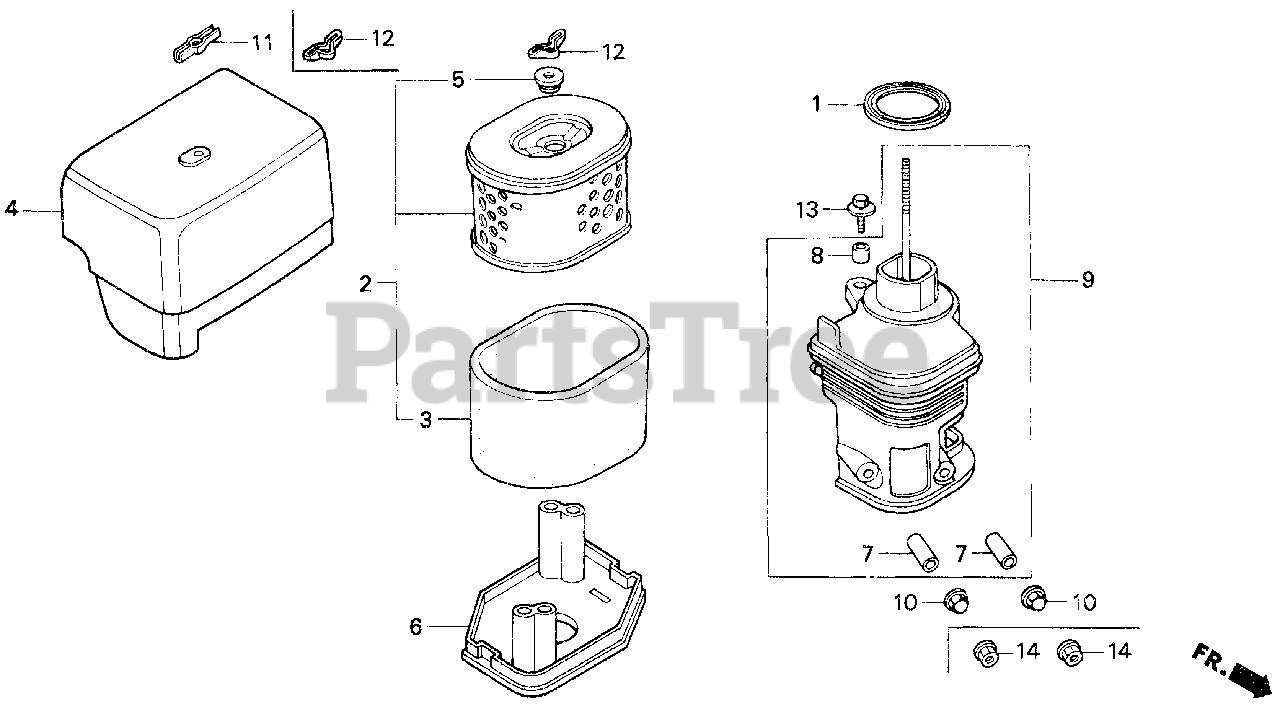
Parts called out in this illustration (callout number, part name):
1	GASKET, ELBOW
2	ELEMENT, AIR CLEANER
3	FILTER (OUTER)
4	COVER, AIR CLEANER
5	GROMMET, AIR CLEANER
6	NOSE, MUFFLER
7	COLLAR, AIR CLEANER
8	COLLAR B, AIR CLEANER
9	ELBOW, AIR CLEANER
10	NUT, CAP (6MM)
11	WINGNUT (6MM)
12	WINGNUT, TOOL BOX SETTING
13	BOLT-WASHER (6X20)
14	NUT, FLANGE (6MM)
